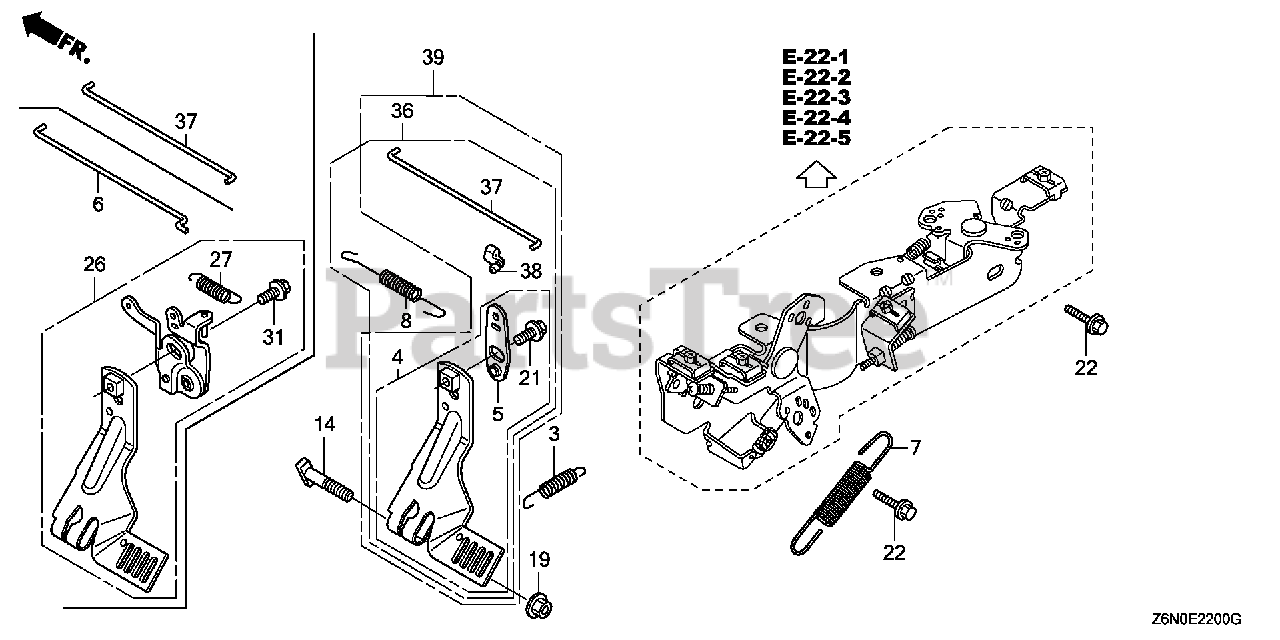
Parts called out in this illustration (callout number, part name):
3	SPRING, STARTER
4	ARM, GOVERNOR
5	ARM, SUB
7	SPRING, GOVERNOR
8	SPRING, THROTTLE RETURN
14	BOLT, GOVERNOR ARM
19	NUT, FLANGE (6MM)
21	BOLT, FLANGE (6X10)
22	BOLT, FLANGE (6X14)
37	ROD, GOVERNOR
38	BUSH, LINKAGE
39	ARM KIT, GOVERNOR
